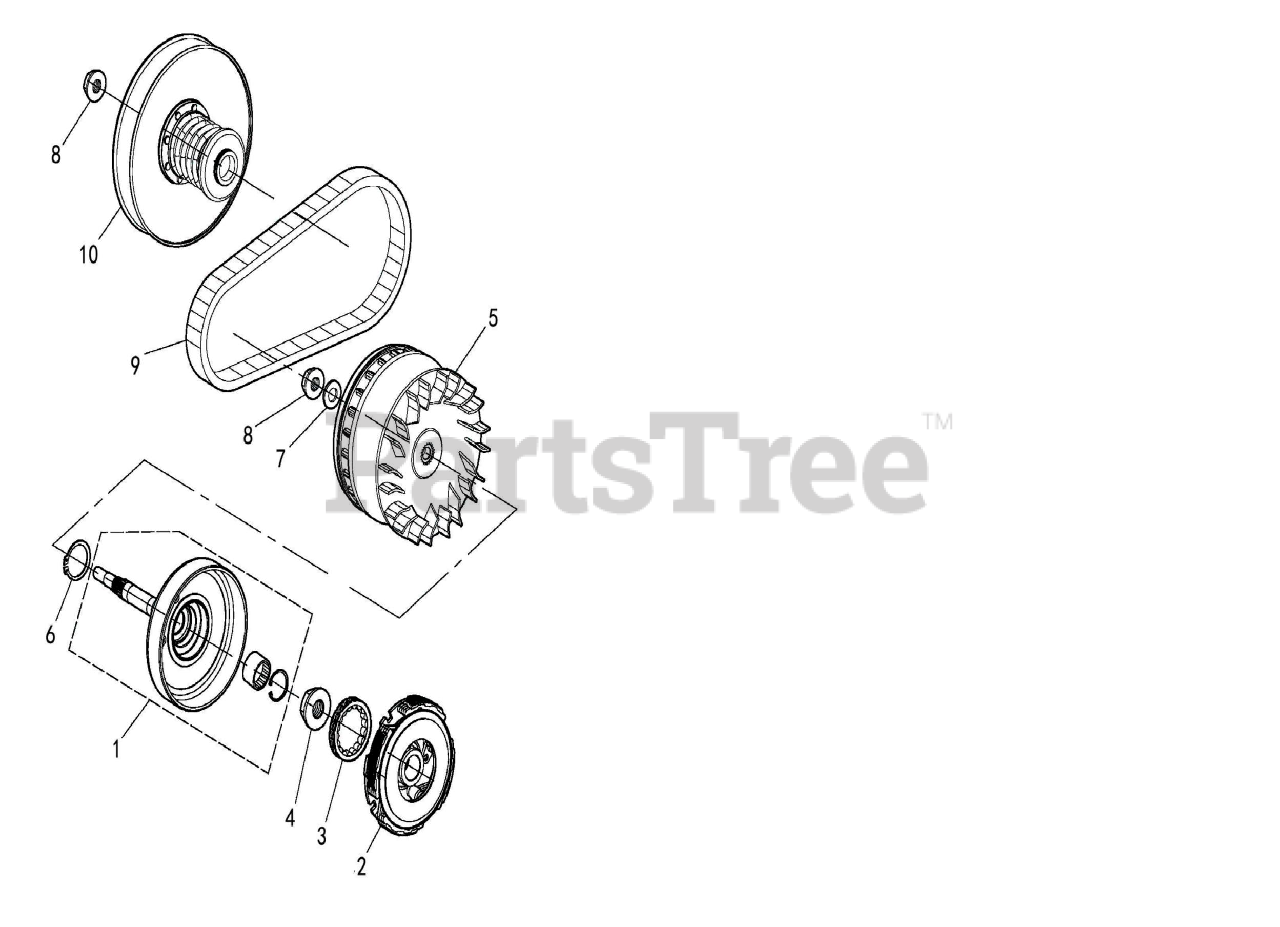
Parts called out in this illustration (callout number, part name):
1	Friction Wheel Assy,Clutch
2	Friction Plate Assy,Clutch
3	Overrunning Clutch Assy
4	Hex Flange Nut M22X1
5	Primary Disc Assy
6	Circlip for shaft ?52
7	Washer 19.2X35X3.2
8	Hex Flange Nut M16X1
10	Driven Pulley Assy
